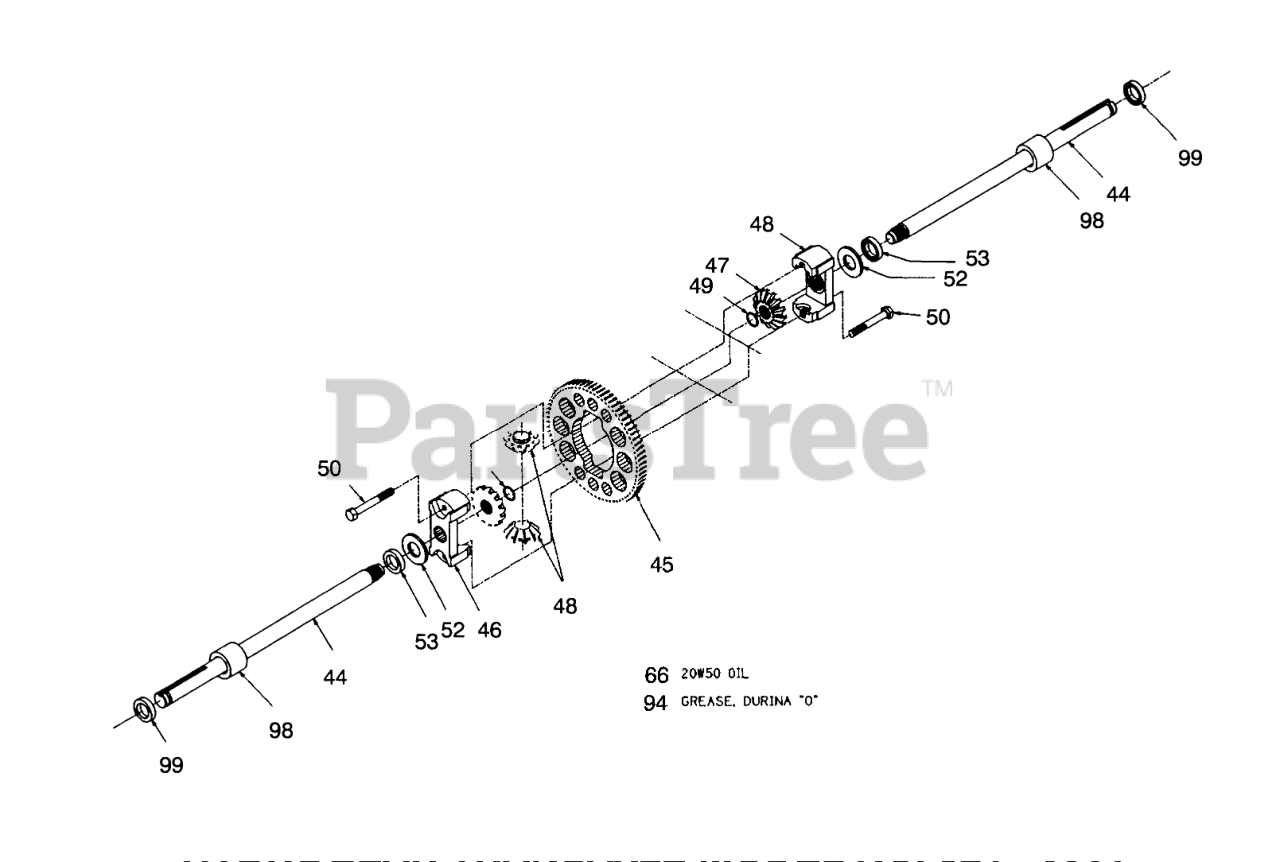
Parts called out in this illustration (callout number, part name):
26	Plate-Bypass
44	Shaft-Axle
46	Housing-Diff.
50	Bolt-Diff. Locking
52	Washer
53	Seal ASM
94	Grease Durina "O"
98	Sleeve-Bearing
99	Seal-Wiper
